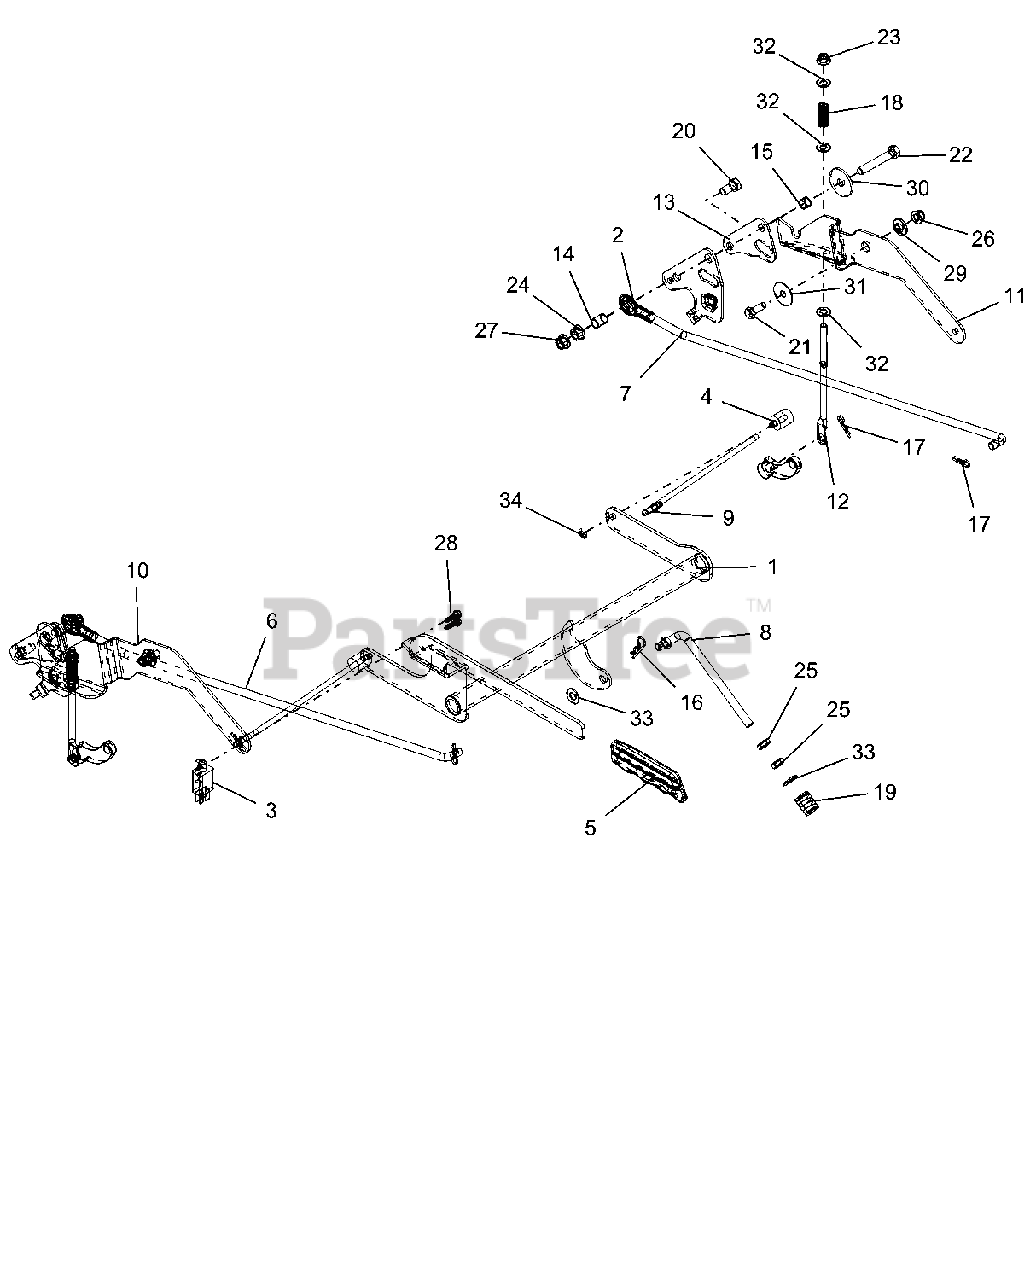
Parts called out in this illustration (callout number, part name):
1	WLDMT, BRAKE LEVER
2	ROD END, .38 RH
3	SWITCH- DOUBLE POLE N.O./N.O.
4	TRUNION, 1/4-20
5	GRIP, PARKING BRAKE (YELLOW)
6	STEERING, LINKAGE RH
7	STEERING, LINKAGE LH
8	LINK, OVER CENTER, PARKING BRK
9	LINK, BRAKE ARM
10	INTERLOCK, RH BRAKE LINK
11	INTERLOCK, LH BRAKE LINK
12	LINK, BRAKE COG
13	PLATE, TRANSAXLE ADAPTOR
14	SPCR, SLV .385X.500X.652
15	SPCR, SLV .385X.500X.350
16	PIN-HAIR CTR .09 X 1.50 YWZC
17	PIN-HAIR INT .08X.18X1.18 YWZC
18	SPRING, COMPRESSION
19	SG-COMP .187X.56X1.62
20	@BLT-HEX .38-16X.75 GR5 YWZC
21	BOLT-HEX.31-18X.875 YWZC GR5
22	@BLT-HEX .38-16X2.25 GR5 YWZC
23	@NUT-LK-CTR-FLG .31-18 YZ GR F
24	NUT-LK-CTR-FLG .38-16 YWZC
25	NUT-HEX-JAM .375-16 YWZC
26	@NUT-LK-NYL-FLG .31-18 YWZC
27	@NUT-LK-TOP-FLG .38-16 YWZC
28	SCR-TAP #12X.75 BOSS INDHXHD
29	BSHG, FLG .325X.499X.26X.88
30	WSHR-FL-STL .380X1.50X.125YWZC
31	WSHR-FL-STL .347X1.254X.048YWZ
32	@WSHR-FL-STL.344X.688X.065YWZC
33	@WSHR-FL-STL.406X.812X.065 YWZ
34	RG-RTNG-EXT .250X.025
